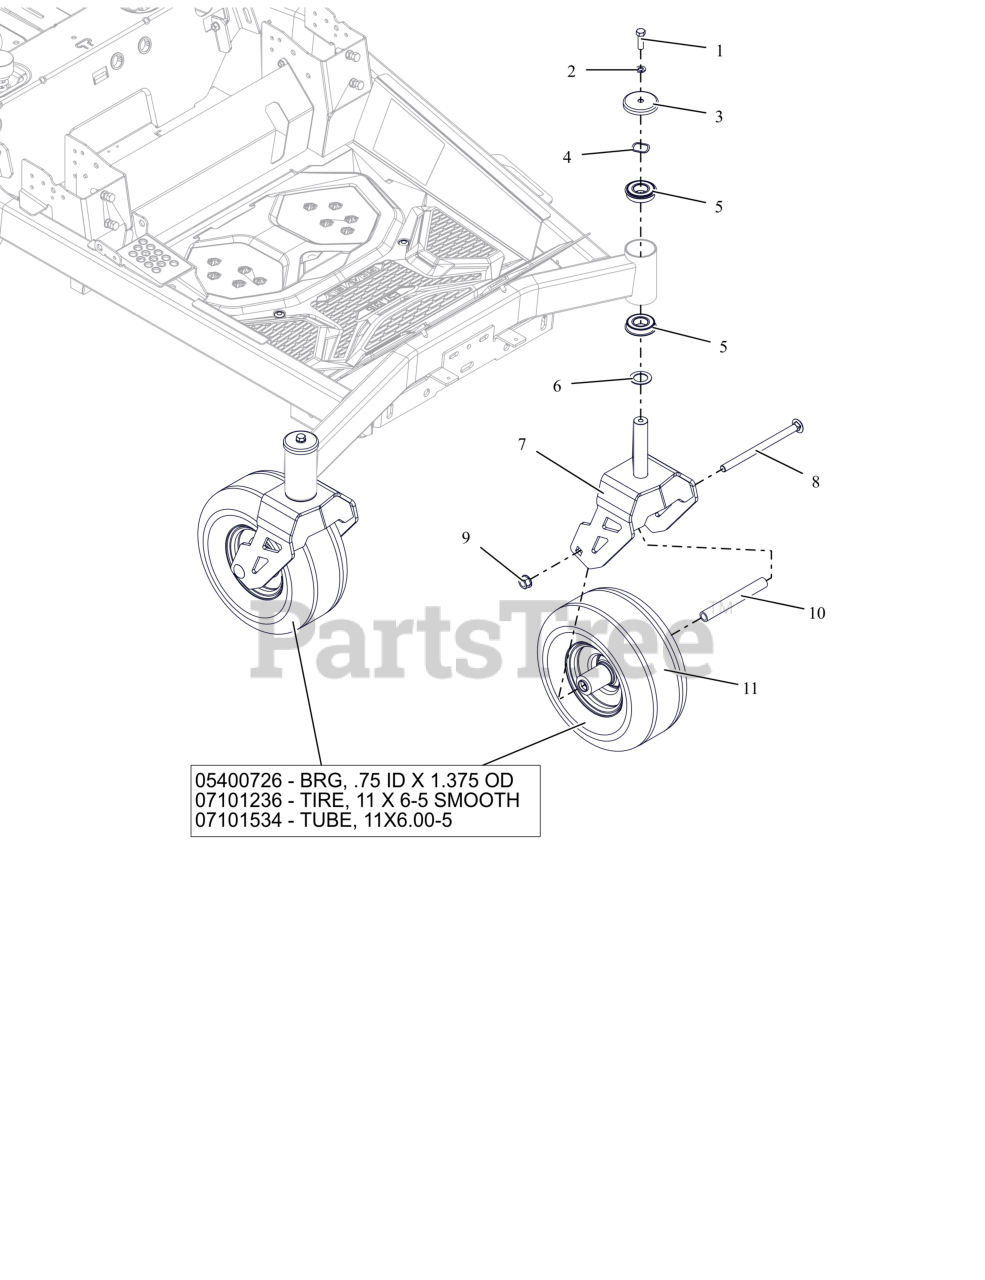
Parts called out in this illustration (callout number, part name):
1	BLT- HEX .38-16X1.25 G5 ZB500
2	WSHR-LK-REG .375X.094 ZB500
3	SHIELD- AXLE BEARING
4	WSHR-WAVE 1.0X1.25X.028 .145FH
5	BEARING, BALL -2.000 OD X 1.000 ID X .5625 W/RING
6	WSHR-HRD-THRS 1.007X1.542X.062
7	WMT-CASTER FORK-MY23-XL
8	BLT-RHSN .50-13X7.50 G5 ZCC NS
9	NUT-LK-CTR-FLG .500-13 GG ZCC
10	SPACER, FRONT WHEEL (WIDE 6.0)
11	TIRE/WHEEL ASSY 11X6-5
11	BRG, .75 ID X 1.375 OD
11	TIRE, 11X6-5 Smooth
11	Tire Tube, 11/6.0-5
